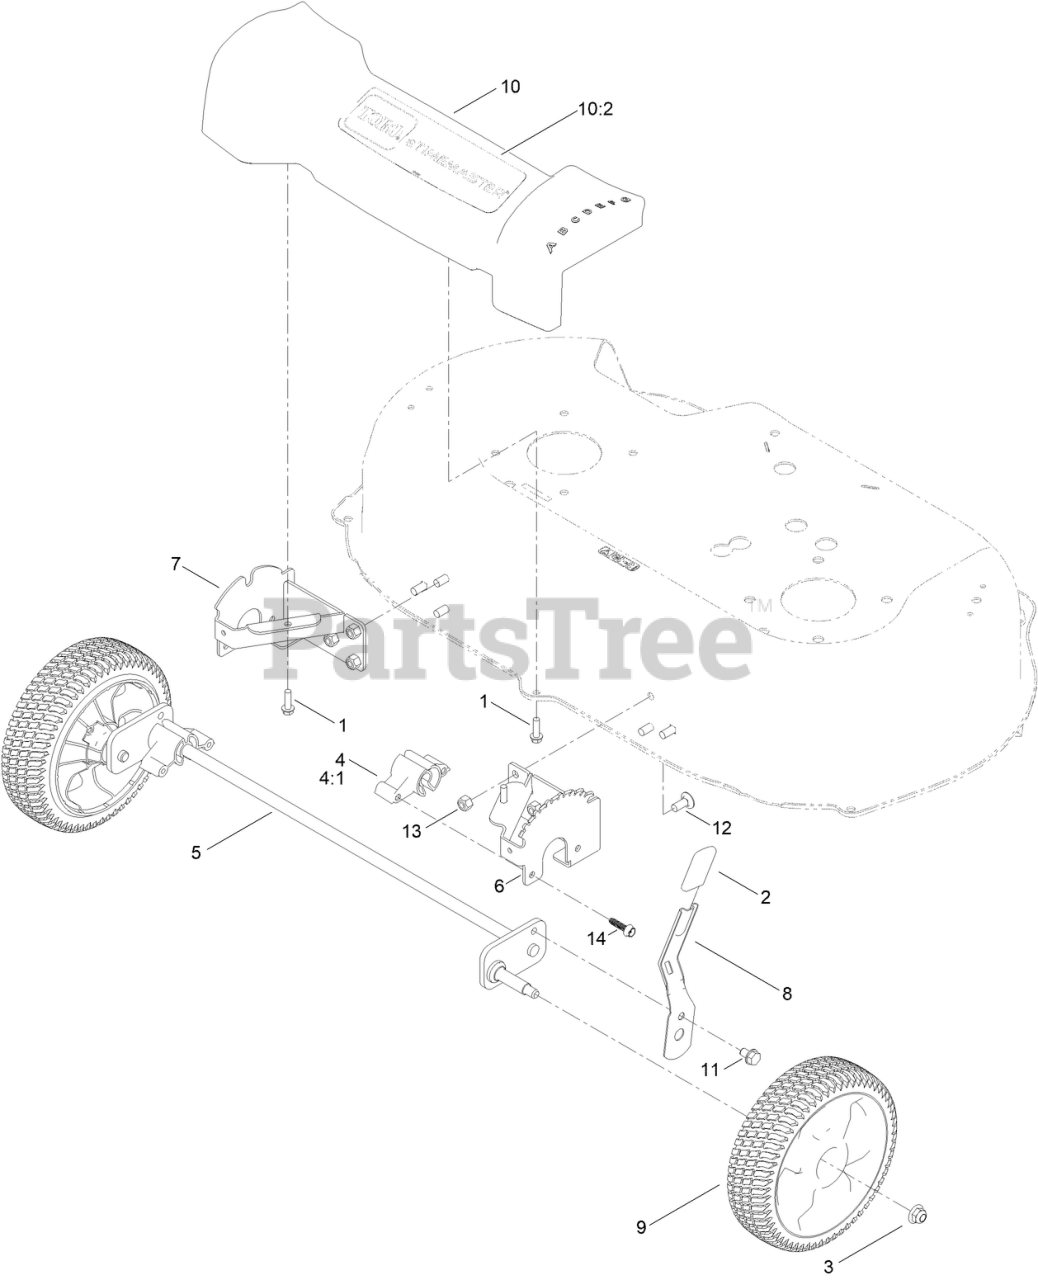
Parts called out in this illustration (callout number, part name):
1	SCREW-HWH
2	GRIP-LEVER
3	NUT-HF, NI
4	BUSHING-PIVOT, FRONT
4:1	RESIN-NYLON 66
5	FRONT AXLE ASM
6	PLATE-HOC, LH
7	PLATE-HOC, RH
8	ARM-SPRING
9	8 INCH WHEEL ASM
10	FRONT COVER ASM
10:2	ARTWORK-TORO TIMEMASTER
11	SCREW-HWH
12	SCREW-CARR
13	NUT-LOCK, NI
14	SCREW-FLANGE, PLASTIC
